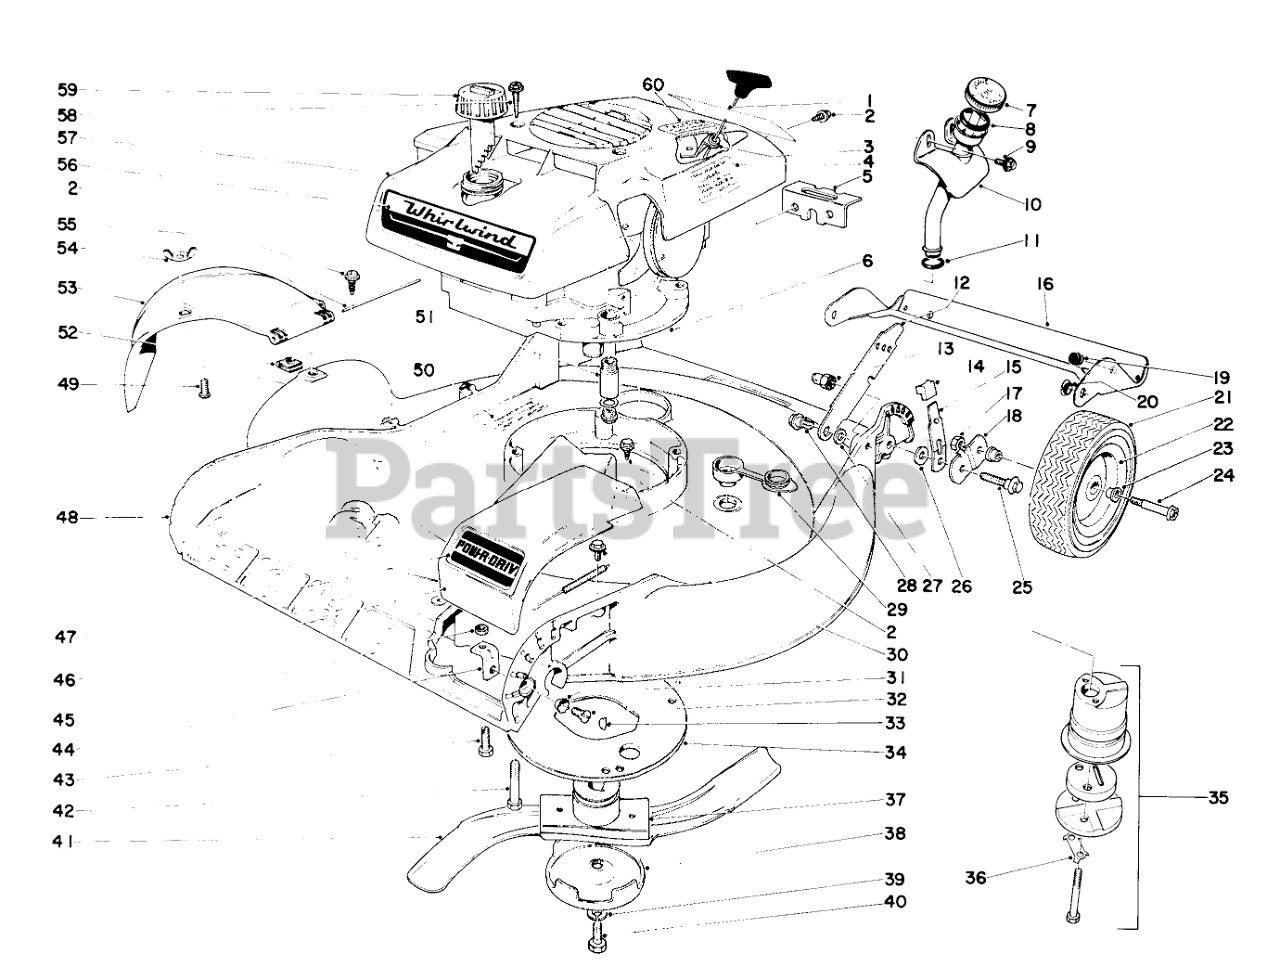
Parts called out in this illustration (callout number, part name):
1	Decal,Maintenance
2	SCREW-HWHTF
3	Bracket,Recoil
4	Decal,Start
5	Bracket
6	Engine
7	Dipstick
8	O-Ring
10	Oiler Tube
11	O-RING
12	Latch
13	Nut
15	Spring Arm
16	Rear Safety Shield (Incl. Ref. Nos. 19)
17	Nut
18	Pivot Arm
19	SKID BUTTON
20	Nyliner
21	8 TIRE
22	Wheel (Incl. Ref. No. 23)
23	FLANGE BUSHING
24	Wheel Bolt
25	Pivot Screw
26	WASHER-PIVOT
27	SPACER
28	SCREW-SHOULDER
29	Washer Plug
30	Screw
31	Lockwasher
33	KEY-WOODRUFF
34	Grass Guard
35	Muffler
36	CLIP - LOCKING
37	BLADE RETAINER WA
38	ANTI-SCALP CUP
39	WASHER-LOCK
40	SPECIAL SCREW
41	Blade
42	3/8-16 X 2-3/4 CAPSCR
43	SCREW
44	ADJ BRACKET
45	NUT-JAM
46	Guard, Belt
47	Decal
48	Housing
50	Decal
51	Extension Oil Drain
52	NUT-SPEED
53	Deflector
54	NUT-WING SPECL
55	HINGE PIN
56	Decal
57	Shroud
58	SCREW-HWH
59	Gas Cap
60	Decal-Warning
